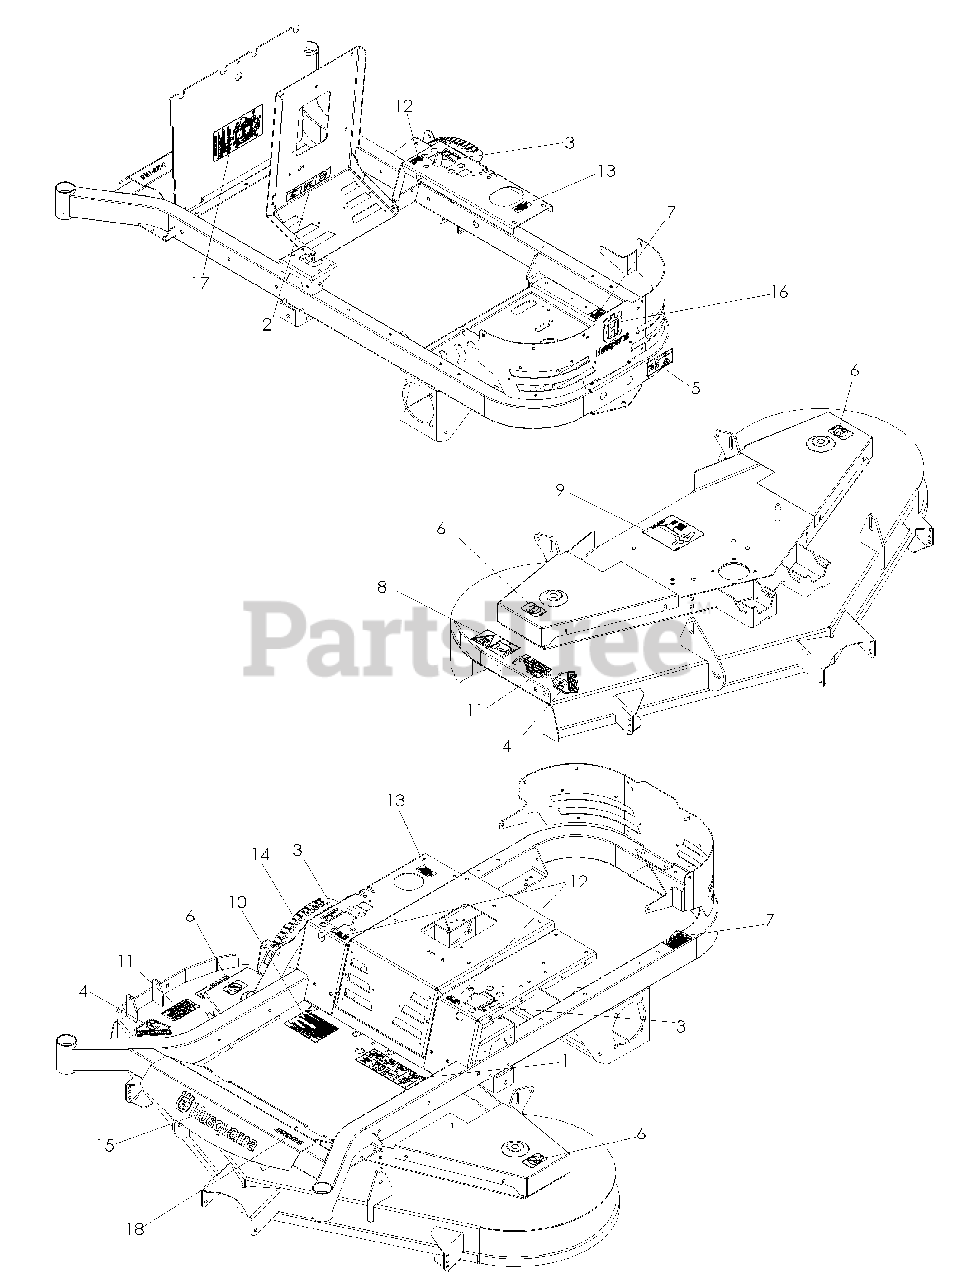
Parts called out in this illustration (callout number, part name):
1	DECAL, WARNING
2	DECAL, BATTERY WARNING
3	DECAL, MOTION CONTROL
4	DECAL, CPSC
5	DECAL, DANGER BLT DRIVE
6	DECAL, NO STEP
7	DECAL, PROP 65
8	DECAL, SEVERING
9	DECAL, BELT ROUTING
10	DECAL, WARNING
11	DECAL, WARNING
12	DECAL, F.S.T
13	DECAL, OIL TANK
14	DECAL, HEIGHT ADJUST
15	DECAL, HUSQ 12" BLUE
16	DECAL, CROWN H, BLUE
17	DECAL, SERVICE
18	DECAL, M5225
18	DECAL, M6125
18	DECAL, M7227
